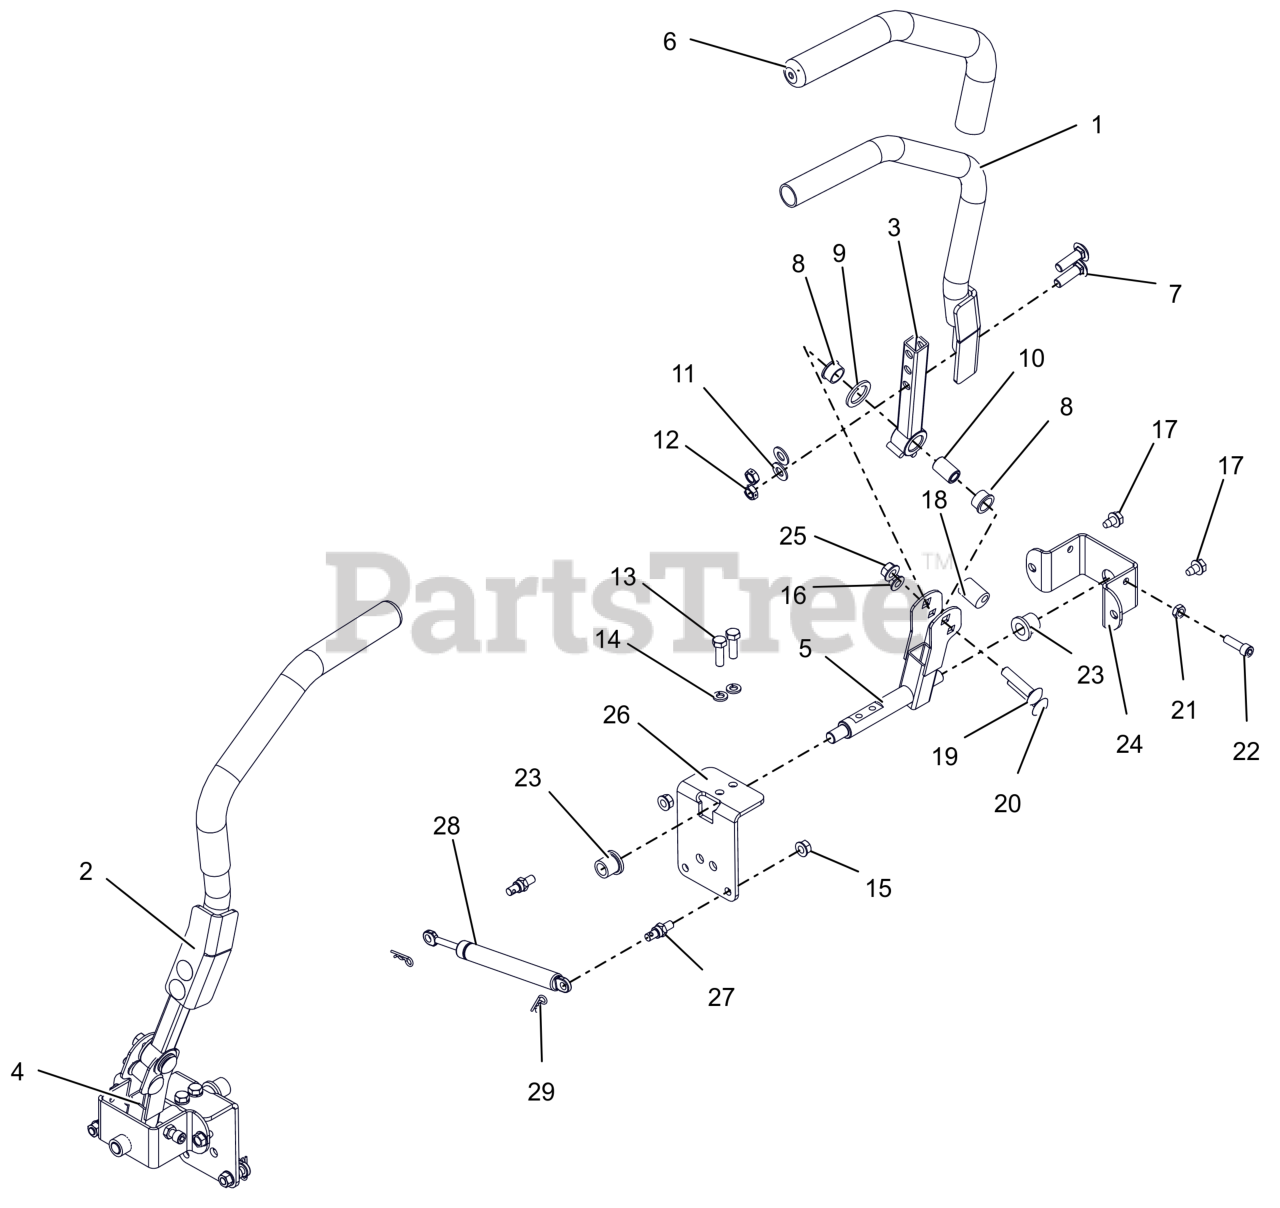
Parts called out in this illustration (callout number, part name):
1	WLDMT, STEERING HANDLE LH
2	WLDMT, STEERING HANDLE RH
3	WLDMT, UPPER CONTROL ARM
4	WLDMT,STEERING ARM LOWER RIGHT
5	WLDMT,STEERING ARM LOWER LEFT
6	GRIP, HANDLEBAR 15" FOAM
7	BLT,RHSSN .38-16X1.25 G5 BFP
8	BSHG-FLG, .625X.75X.450X.875
9	WASHER, FRICTION .875X1.25X.10
10	SPACER, .375X.625X.970 (PM)
11	WSHR,FLT .406X.812X.065 ZCC
12	@NUT-LK-CTR-JAM .375-16 YWZC
13	BLT, HEX .31-18X1.00 G8 ZCC
14	WSHR,LK-REG .312X.078 ZCC
15	NUT-LK-TOP-FLG .312-18 GF ZCC
16	NUT,LK-NYL-FLG .31-18 G5ZC120
17	SCR,TAP .312-18X.50 HWH TR ZCC
18	BSHG,ECCEN .328X.750X1.01 PM
19	BLT,RHSSN .38-16X1.75 G5 BFP
20	BLT,RHSSN .31-18X1.75 G5 BFP
21	NUT-JAM .312-18 G2 ZCC
22	SCR, SKH .312-18X1.00 G8 SS
23	BSHG-FLG .515X.750X.745X1.00NY
24	BRKT, STEERING
25	NUT-LK-CTR-FLG .375-16 GF ZCC
26	BRKT, STEEERING
27	COUPLER, DAMPER MOUNT
28	DAMPER, STRAIGHT MOUNT
29	PIN, HAIR #213 .08X1.19 ZCC
